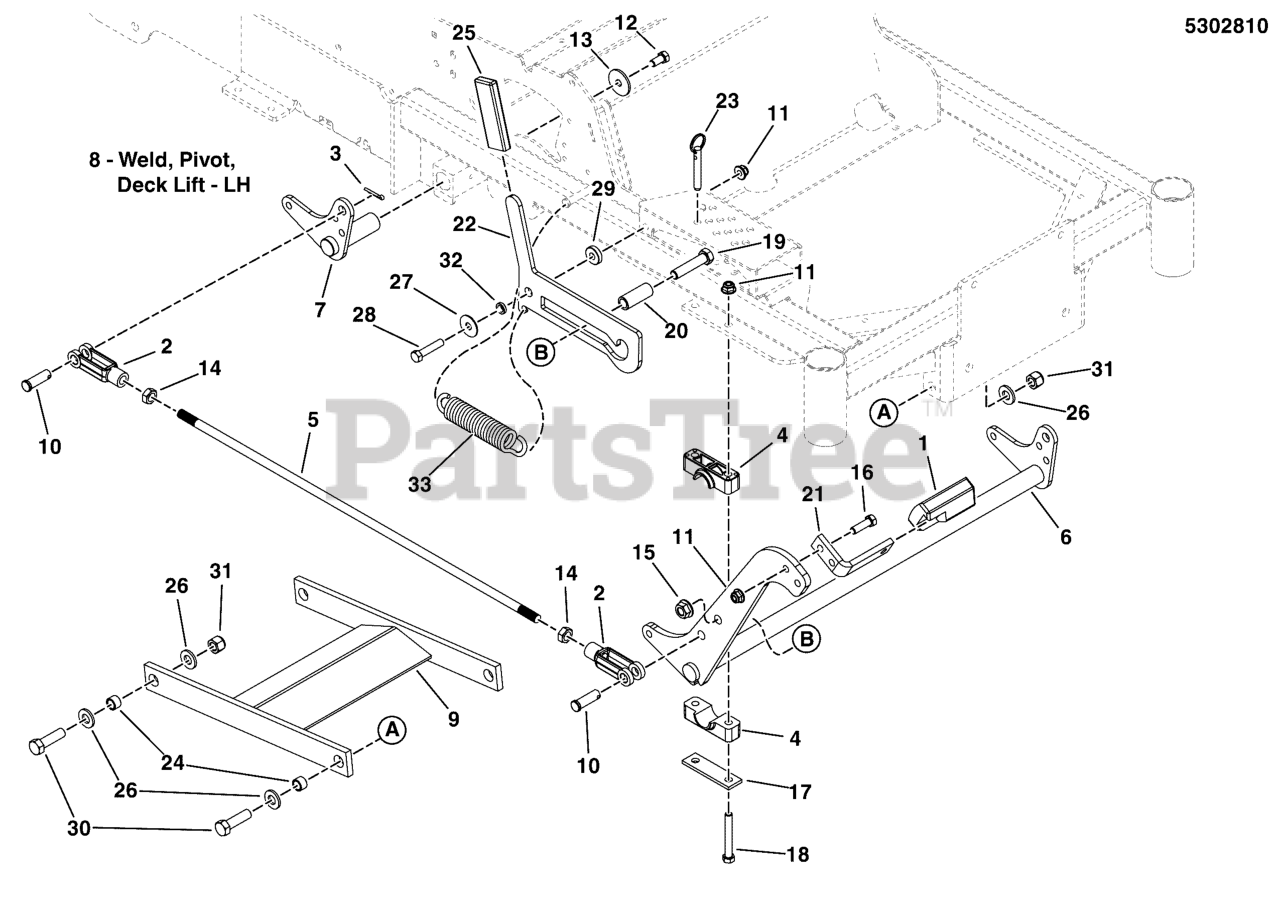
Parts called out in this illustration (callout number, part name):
1	PEDAL, Rubber
2	CLEVIS, 1/2-20, STEEL
3	PIN, COTTER, 1/8 X 3/4
4	PIVOT BLOCK, PLASTIC
5	ROD, DECK LIFT, SNAPPER PRO
6	WELD, FRONT DECK PIVOT - RED
7	WELD, PIVOT, DECK LIFT, RH - BLK
9	WELD, PULLER BAR - BLK
10	PIN, CLEVIS, 1/2 X 1 1/2, YZP
11	NUT, 3/8-16 HEX NYLOCK FLANGE
12	BOLT, 3/8-16 X 3/4, PLT W/PATCH
13	WASHER, .390 X 1.50 X .109, YZ
14	NUT, 1/2-20 HEX JAM
15	NUT, Hex Flange, Nylock, 1/2-13
16	BOLT, 3/8-16 X 1-1/4" GD5 CZ
17	PLATE, PIVOT BLOCK SUPPORT - BLK
18	BOLT, 3/8-16 X 2-3/4" GD5 CZ
19	BOLT, 1/2-13 X 4-1/2 GD5 YZ
20	SPACER, .53 X .73 X 3.38, CZ
21	PEDAL, FOOT - BLK
22	PLATE, DECK TRANSPORT LEVER - RED
23	HITCH PIN, 3/8 X 2-1/2, COTTERLESS, CZ
24	INSERT, BEARING
25	GRIP, FOAM, 1/4 X 1 X 4.1
26	WASHER, 1/2 GD9 YZ
27	WASHER-3/8 FENDER
28	BOLT, 3/8-16 X 1-3/4" GD5 CZ
29	SPACER, .39 X 1.00 X .25
30	BOLT, 1/2-20 X 1-3/4" GD8 CZ
31	NUT, Hex, Nylon Lock, 1/2-20
32	SPACER, .38 X .50 X .27, CZ
33	SPRING, EXTENSION, .50OD X 4.12 FL
